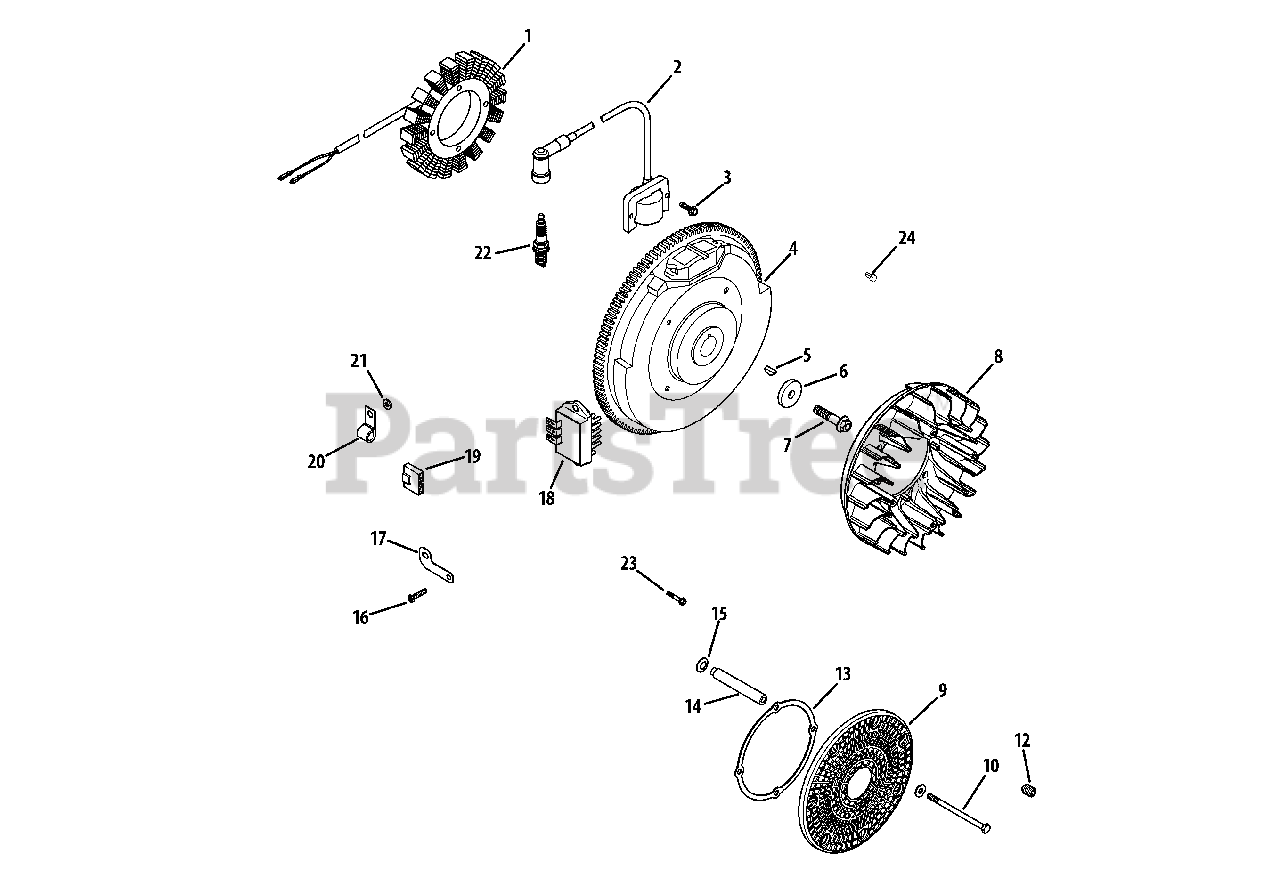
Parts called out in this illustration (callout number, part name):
1	25 Amp Stator Assembly Kit
2	Module Ignition Kit (CDI Fixed)
3	Thread Forming Screw
5	Key, 3/16 x 5/8
6	Flat Washer, 13/32
7	Flange Screw, M10 x 1.5 x 45
8	Fan
10	Cap Screw, M6 x 1.0 x 99.5
11	Flat Washer, 1/4 x 5/8
12	Socket Set Screw, #10-24 x 1/4
13	Support Ring
15	Spring Washer, 10 MM
16	Hex Flange Hi-Lo Screw
17	Ground Strap Bracket
18	Rectifier Regulator
20	Cable Clip
21	Flat Washer, 1/4 x 1/2
22	Spark Plug (Std.)
23	Flange Screw, M8 x 1.25 x 45
24	Washer Head Tap Screw, #8-18 X 1/2
